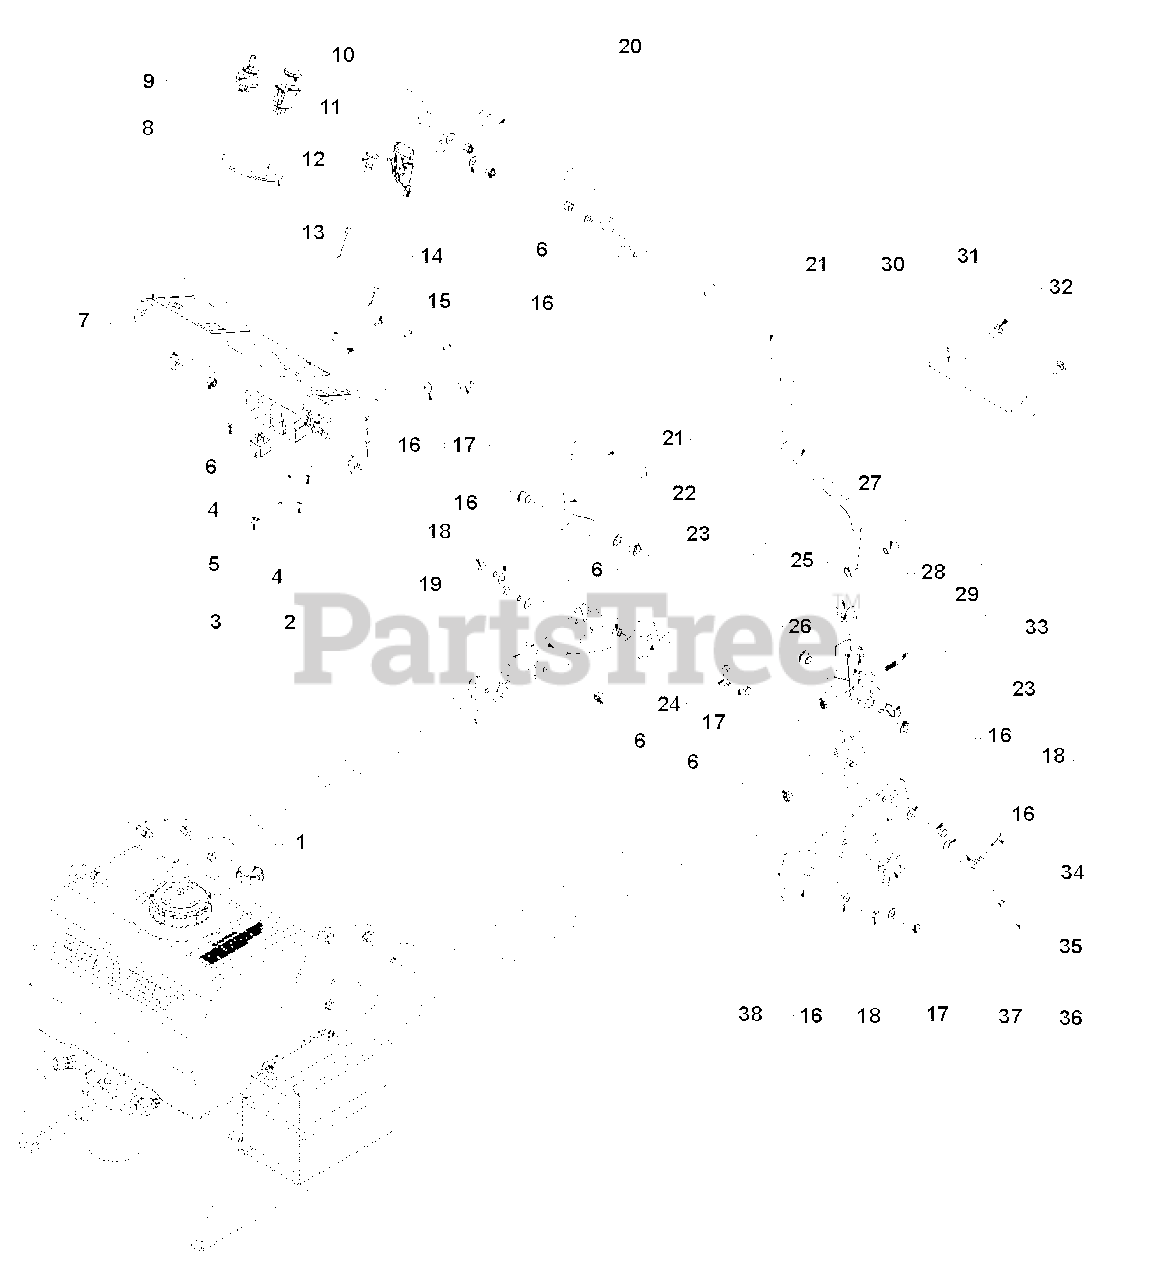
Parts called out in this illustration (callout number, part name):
1	Cap, Oil Fill Breather
2	Washer, #8 Medium Spring Lock
3	Nut, .38-24 Standard Hex
4	Nut, 8-32 Standard Hex
5	Relay, ISO Mini Electric
6	Locknut, .38-16 Nyloc
7	Weldment, Handle Brace
8	Console, Loop Handle Hydro
9	Switch, Key- 3 Position
10	Cable, Throtle 49.5"
11	Switch, PTO Engagement
12	Cable, Choke 48.0"
13	Trim, Rubber Edge 12"
14	Screw, 8-32 x .50
15	Screw, 8-32 x .500 Round Head Machine
16	Washer, .406 x .813 x .065 Flat
17	Bolt, .38-16 x 1.00 Hex 5
18	Bolt, .38-16 x 1.25 Hex 5
19	Weldment, Right Hand Control Mount
20	Handle, Loop Hydro
21	Grip, Control
22	Weldment, Right Hand Drive Lever
23	Bearing, Flange .500 x .625 x .500
24	Weldment, Pin and Lock
25	Switch, Seat Overide
26	Locknut, .3125-18 Nyloc
27	Spacer, .500 x .330 x .980
28	Weldment, Left Hand Handle Mount
29	Bolt, .3125-18 x 1.75 Hex 5
30	Weldment, Left Hand Drive Lever
31	Drive Arm Back Plate
32	Bolt, .38-16 x .750 Round Head Square Neck
33	Spring, Torque 1.00 x .062
34	Pin, Spring
35	Lever, Lock Y Assembly
36	Lever, Lock Y Assembly
37	Knob, Star .38-16 x 1.00
38	Weldment, Left Hand Control Mount
